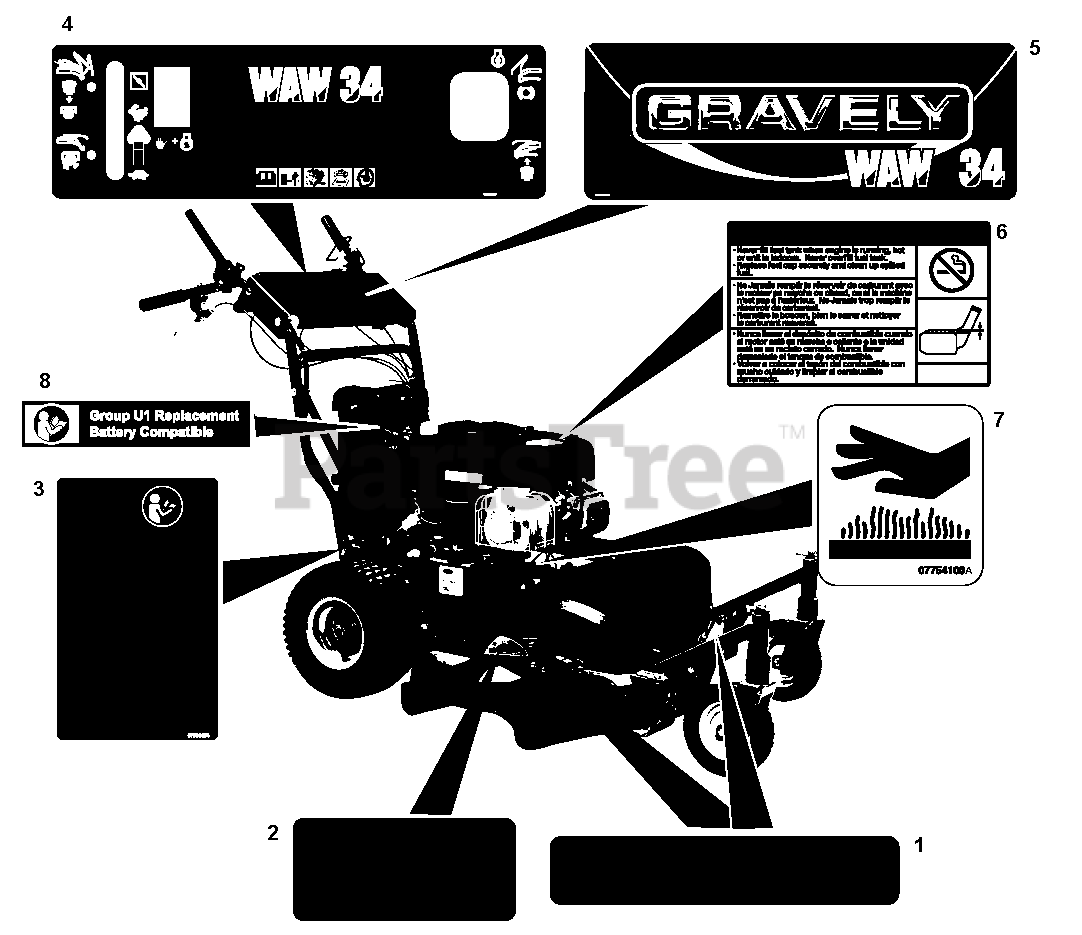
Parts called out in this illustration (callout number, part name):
1	Decal, Deck Safety
2	Decal, Deck Guarding Safety
3	Decal, Main Safety
4	Decal, CE WAW Operational
5	Decal, WAW 34 Gravely Dash
6	Decal, Fuel, Warning
7	Decal, Hot Surface
8	Decal, U1 Battery Replacement
